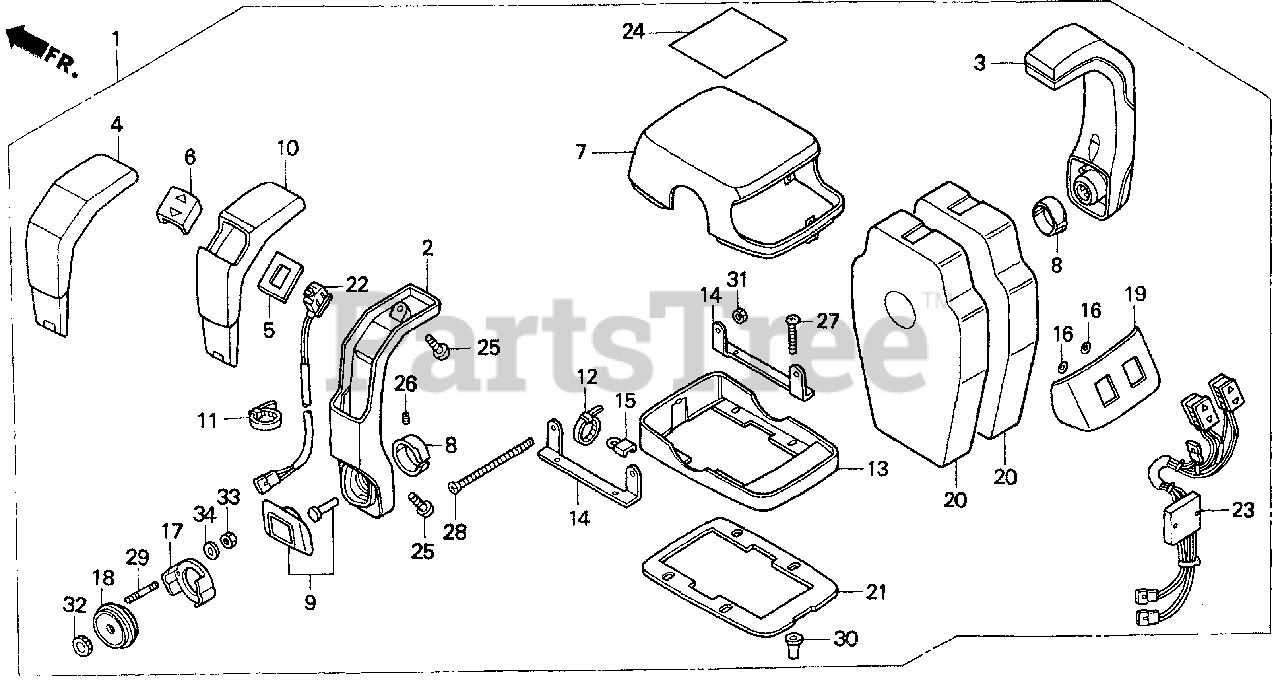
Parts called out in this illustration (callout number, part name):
1	BOX ASSY., REMOTE CONTROL (TOP MOUNT DUAL) (NA USE ALT:24800-ZW7-V11) Use up to Frame SN 1004789.
2	HANDLE ASSY., REMOTE CONTROL Use up to Frame SN 1004789.
3	HANDLE, REMOTE CONTROL Use up to Frame SN 1004789.
4	GRIP, REMOTE CONTROL HANDLE Use up to Frame SN 1004789.
5	PLATE, SWITCH SETTING Use up to Frame SN 1004789.
6	COVER, GRIP Use up to Frame SN 1004789.
7	HOUSING ASSY., REMOTE CONTROL BOX (A) Use up to Frame SN 1004789.
8	BUSHING Use up to Frame SN 1004789.
9	BUTTON ASSY. Use up to Frame SN 1004789.
10	GRIP, REMOTE CONTROL HANDLE (L) Use up to Frame SN 1004789.
11	BAND A, CABLE Use up to Frame SN 1004789.
12	BAND B, CABLE Use up to Frame SN 1004789.
13	HOUSING ASSY., REMOTE CONTROL BOX (B) Use up to Frame SN 1004789.
14	BRACKET, REMOTE CONTROL HOUSING Use up to Frame SN 1004789.
15	ANCHOR Use up to Frame SN 1004789.
16	RING Use up to Frame SN 1004789.
17	BRACKET, SWITCH MOUNTING Use up to Frame SN 1004789.
18	PLATE ASSY., SWITCH MOUNTING Use up to Frame SN 1004789.
19	MARK, REMOTE CONTROL HOUSING Use up to Frame SN 1004789.
20	HOUSING ASSY. (INNER) (TOP MOUNT) Use up to Frame SN 1004789.
21	GASKET Use up to Frame SN 1004789.
22	SWITCH ASSY., POWER TRIM-TILT (A) Use up to Frame SN 1004789.
23	SWITCH ASSY., POWER TRIM-TILT (B) Use up to Frame SN 1004789.
24	MARK, REMOTE CONTROL (DUAL) Use up to Frame SN 1004789.
25	SCREW (10-32X1") Use up to Frame SN 1004789.
26	SCREW SET (1/4-20X16") Use up to Frame SN 1004789.
27	SCREW (10-32X1-1/2") Use up to Frame SN 1004789.
28	SCREW (10-32X4") Use up to Frame SN 1004789.
29	STUD (10-32X2") Use up to Frame SN 1004789.
30	NUT, WELDING (10-32) Use up to Frame SN 1004789.
31	NUT (10-32) Use up to Frame SN 1004789.
32	NUT, LOCK (15/32-32) Use up to Frame SN 1004789.
33	NUT (10-32) Use up to Frame SN 1004789.
34	WASHER Use up to Frame SN 1004789.
